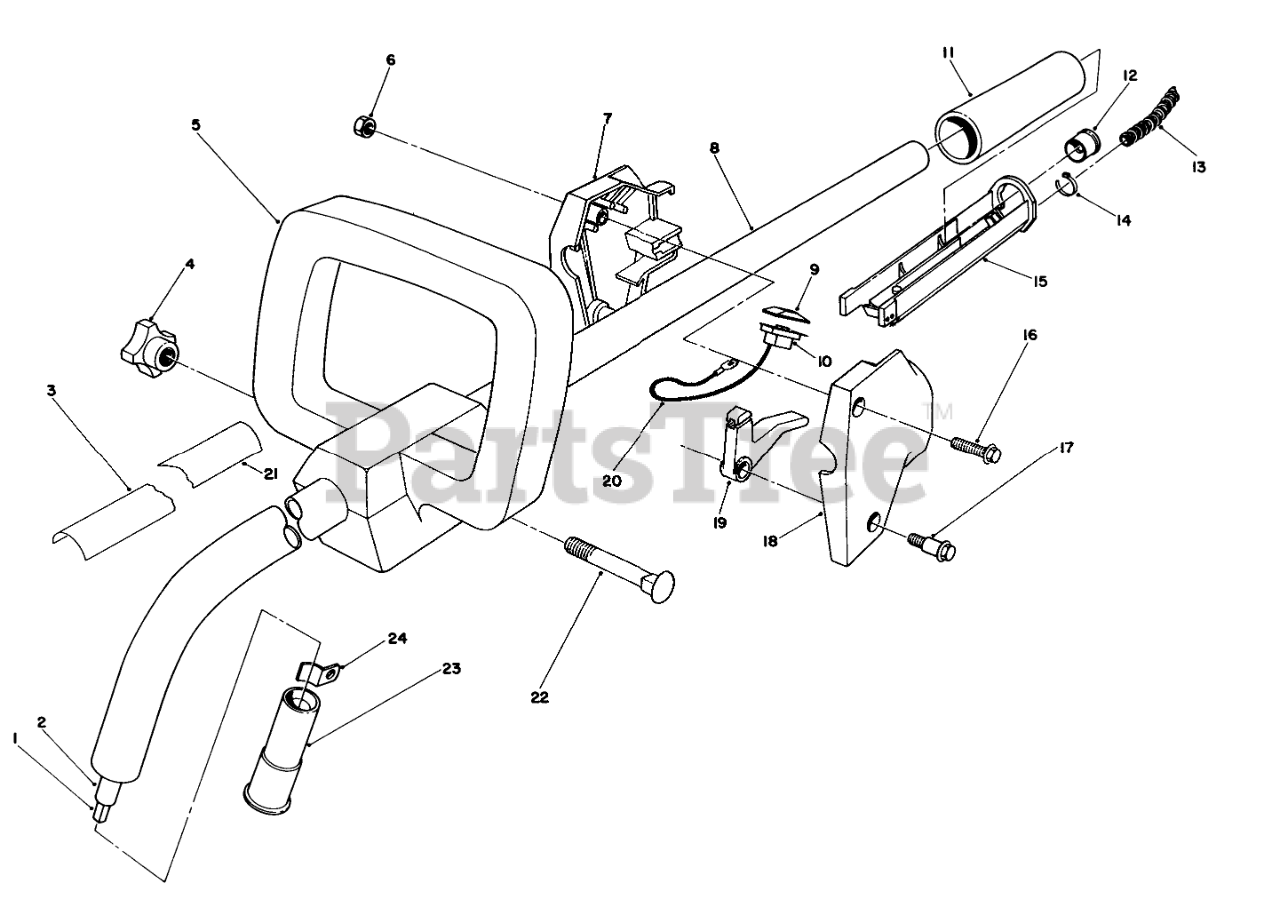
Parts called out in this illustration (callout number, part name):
1	FLEX SHAFT
2	FLEX SHAFT CASING ASM
3	Decal-Model No.
4	Knob
5	SECONDARY HANDLE
6	NUT-LOCK, NI
7	RH HOUSING
8	Tube-Curved
9	SWITCH COVER
10	SWITCH
11	GRIP-RUBBER
12	BUSHING
13	CABLE COVER
14	RING FITTING
15	TROUGH
17	SCREW-SHOULDER
18	LH HOUSING
19	THROTTLE LEVER
20	WIRE ASM
21	Decal
22	BOLT-CARRIAGE
23	INSERT-POLE END
24	LOWER TUBE RETAINER
